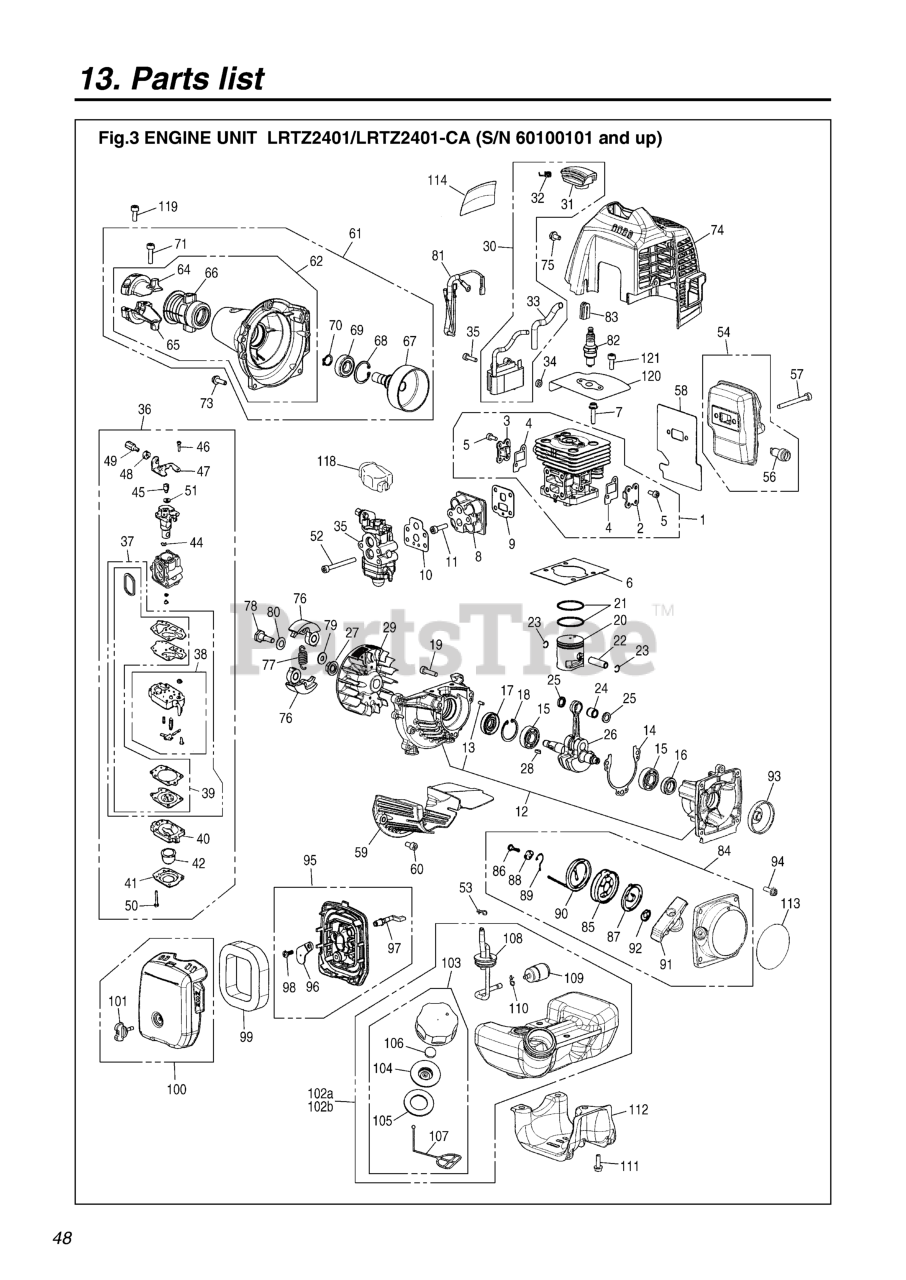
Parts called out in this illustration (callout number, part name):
1	CYLINDER-C
2	COVER, TR-S
3	COVER, TR-F
4	GASKET, TR
5	BOLT, TORX
6	GASKET, BASE
7	BOLT
8	INSULATOR
9	GASKET
10	GASKET, CARB
11	BOLT, TORX
12	CRANKCASE-C
13	PIN
14	GASKET, CASE
15	BEARING
16	SEAL
17	SEAL, OIL (RPLS 1140-21220)
18	RING, SNAP, M28 x 1.2
19	BOLT (RPLS 2850-14220)
20	PISTON
21	RING, PISTON
22	PIN, PISTON
23	RING, SNAP (RPLS 1101-41320)
24	BEARING
25	WASHER
26	CRANKSHAFT-C
28	KEY
29	ROTOR
30	COIL ASSY
31	CAP (RPLS 4810-72110)
32	SPRING
33	TUBE
34	SPACER (RPLS -71260)
35	BOLT TORX
36	CARBURETOR-A (BCZ2401S)
37	REBUILD KIT
38	BODY, PUMP
39	KIT, GASKET (REPLACES-06020)
40	BODY, PURGE
41	COVER, PUMP
42	PUMP, PRIMING
44	RING
45	SWIVEL
46	SCREW
48	NUT, CABLE ADJUSTER
49	SCREW, CABLE ADJUSTER
50	SCREW
51	WASHER
52	BOLT
53	CLIP
54	MUFFLER-A
56	ARRESTER
57	BOLT
58	GASKET, MUFFLER
59	PLATE
60	BOLT
61	HOUSING ASSY (RPLS T1551-31000
62	HOUSING COMP (RPLS. -31110)
64	BRACKET (A) (RPLS -31211)
65	BRACKET (B)
66	CUSHION (RPLS -31231)
67	DRUM (REPLACES 4810-31122)
68	RING, SNAP, M28 x 1.2
69	BEARING
70	RING, SNAP (RPLS 3130-13270)
71	BOLT (RPLS 2850-14220)
73	BOLT
74	COVER, ENGINE
75	BOLT (RPLS. T4950-51011)
76	SHOE
77	SPRING
78	BOLT
79	WASHER, FLAT (USE 182303)
80	WASHER (RPLS -51241)
81	CORD COMP.
82	SPARK PLUG
83	GROMMET
84	RECOIL-A
85	REEL
86	SCREW
87	SPRING, SPIRAL
88	COLLAR
89	ARM
90	ROPE (REPLACES 4500-75160)
91	KNOB (RPLS -75420)
92	PLATE, STOPPER
93	PULLEY
94	BOLT, TORX
95	BODY ASSY (RPLS T1551-82100)
96	PLATE, CHOKE
97	LEVER
98	SCREW
99	ELEMENT
100	COVER-A (RPLS T1551-82200)
101	KNOB
102A	TANK ASSY
103	CAP ASSY (RPLS -85201)
104	HOLDER (REPLACES -85230)
105	PACKING
106	FILTER
107	STOPPER
109	FILTER ASSY
110	CLIP (REPLACES 2841-31280)
111	BOLT
112	GUARD, TANK
113	LABEL, RECOIL
114	LABEL, COVER
118	COVER
119	BOLT
120	PLATE
121	BOLT
